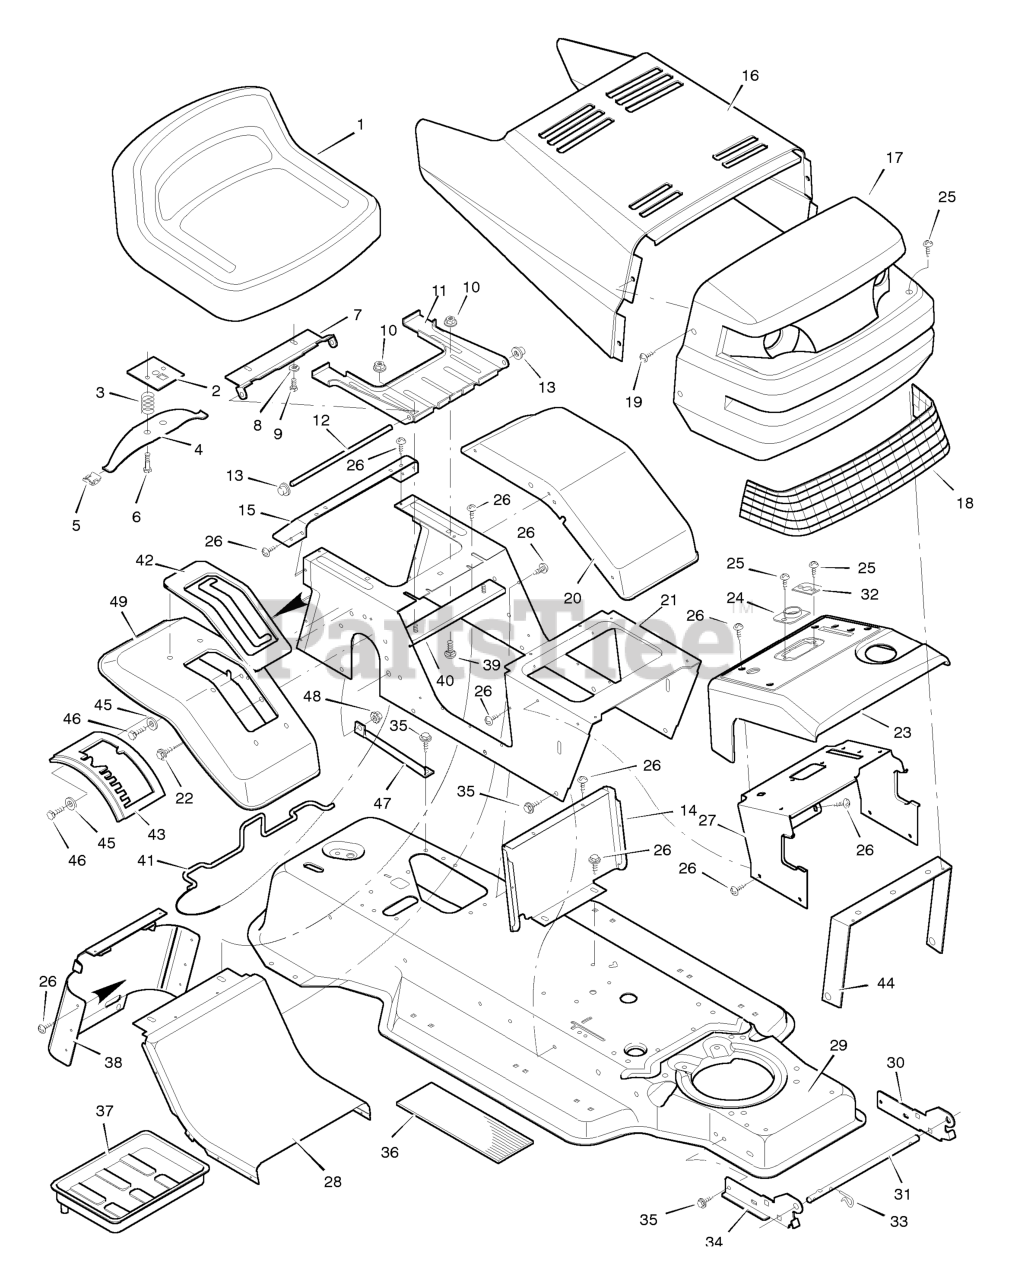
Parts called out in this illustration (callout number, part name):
2	Plate Assembly, Switch
3	Spring, Compression
4	Spring, Seat
5	Glide, Spring
6	Bolt, Shoulder
7	Support, Seat
8	Lockwasher
9	Bolt, Hex
10	Locknut, Flange
11	Bracket, Pivot
12	Rod, Pivot
13	Cap, Push On
14	Insert, Front
15	Fender, Apron
17	Grille Assembly
21	Console Assembly
23	Dash Panel
24	Bearing, Steering
26	Screw
27	Support, Dash
28	Insert, Rear
29	Frame Assembly
30	Bracket, Left Grille
31	Rod, Pivot
32	Bearing
33	Pin, Hair
34	Bracket, Right Grille
37	Tray, Battery
38	Cap, Console
39	Bolt
40	Channel Assembly
41	Clamp, Battery
42	Cover, Shift
43	Gate, Shift
44	Brace, Grille
45	Washer
46	Bolt, Hex
47	Strut, Shifter
48	Locknut
49	Fender, SOG
